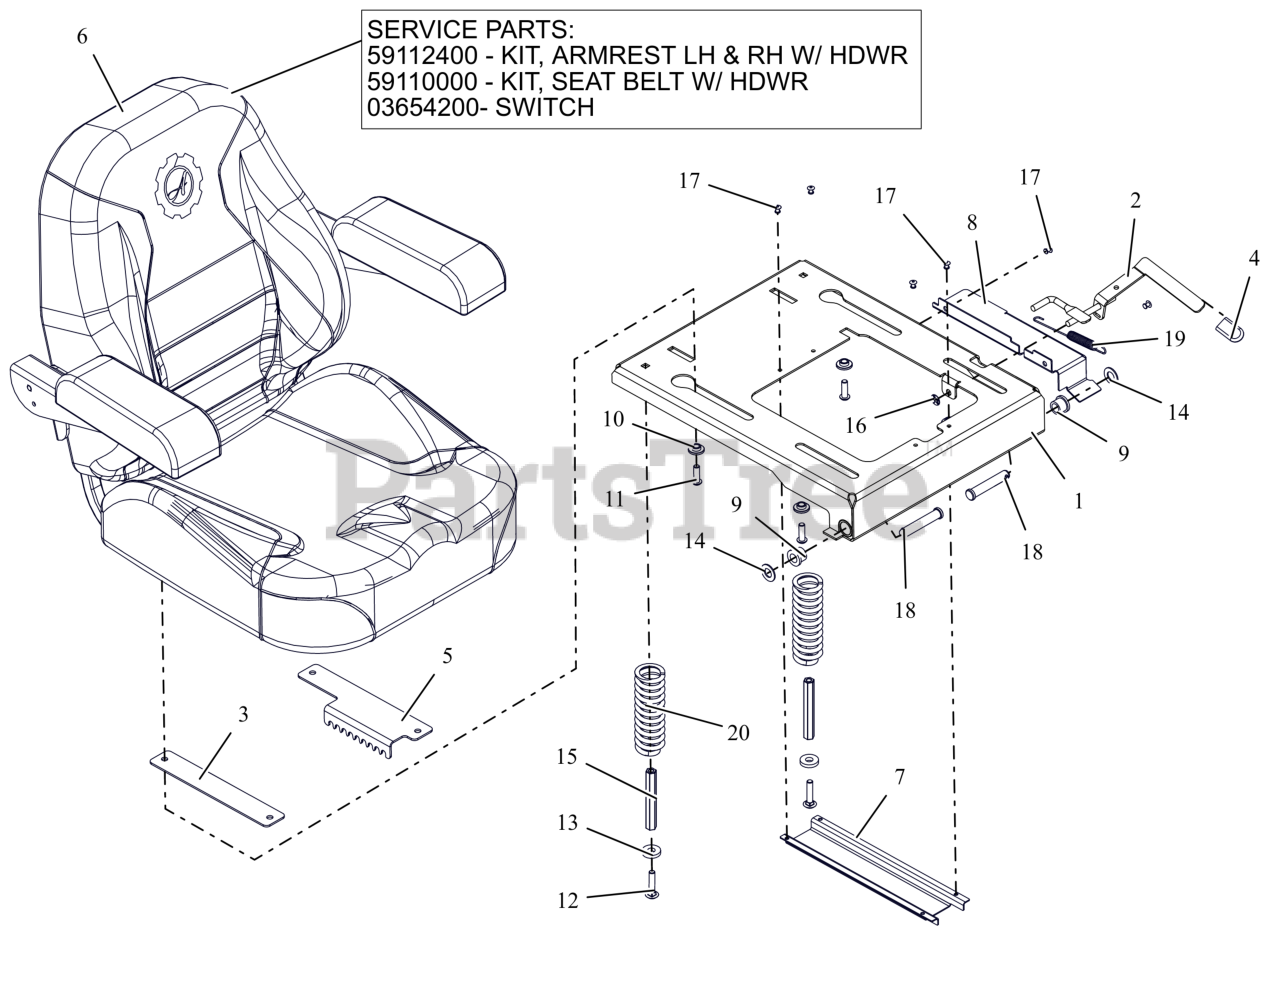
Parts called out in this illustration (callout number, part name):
1	WLDMT, SEAT PLATE HD
2	WLDMT, SEAT SLIDE LEVER
3	PLATE, ADJUSTABLE SEAT SLIDE
4	GRIP, SEAT LEVER, GREY
5	PLATE, HD SEAT ADJUSTMENT
6	SEAT, APEX
6	KIT-LH & RH ARM REST-05124700
6	SWITCH- SEAT
7	GUARD,SEAT SWITCH
8	GUARD, SEAT PLATE CE
9	BSHG, FLG .516X.750X.625X.937
10	BSHG-FLG .325X.499X.3X.875
11	BLT,SHCS-BTN .31-18X1.00 ZCC
12	BLT,RHSN .31-18X1.50 G5 ZCC
13	WSHR, FLT .406X1.00X.188 ZCC
14	WSHR, FLT .531X1.00X.063 ZCC
15	NUT, COUPLING 5/16X18 X 3.75
16	NUT-PUSH .312
17	RIVET, .1875 AL/AL .126-.250
18	PIN-CLIC .50X2.70X2.31 -ZCC
19	SG-TENS .06X.482X5.35
20	SPRING, COMPRESSION SEAT 224LB
